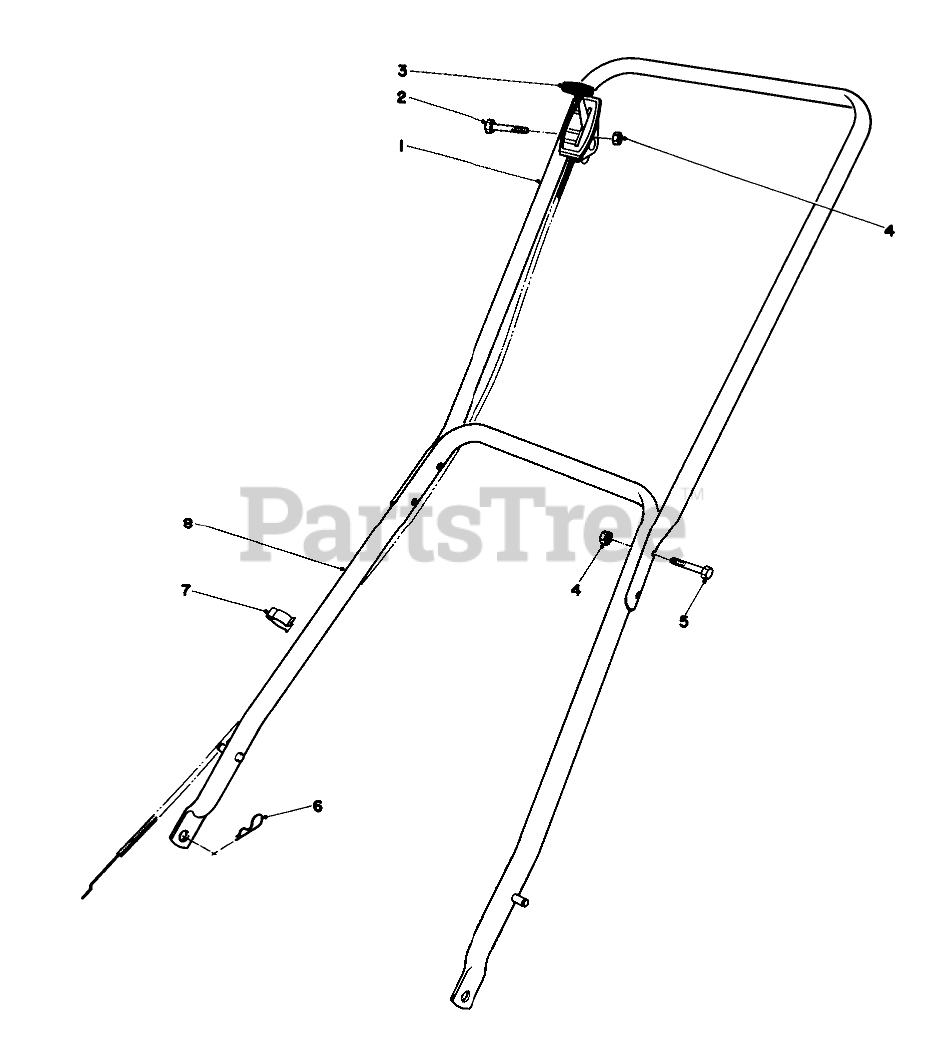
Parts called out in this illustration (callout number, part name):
1	UPPER HANDLE
2	SCREW-HH
3	Throttle Control
4	NUT-LOCK
5	SCREW-HH
6	PIN-COTTER, HAIR
7	Clamp
8	LOWER HANDLE WA
